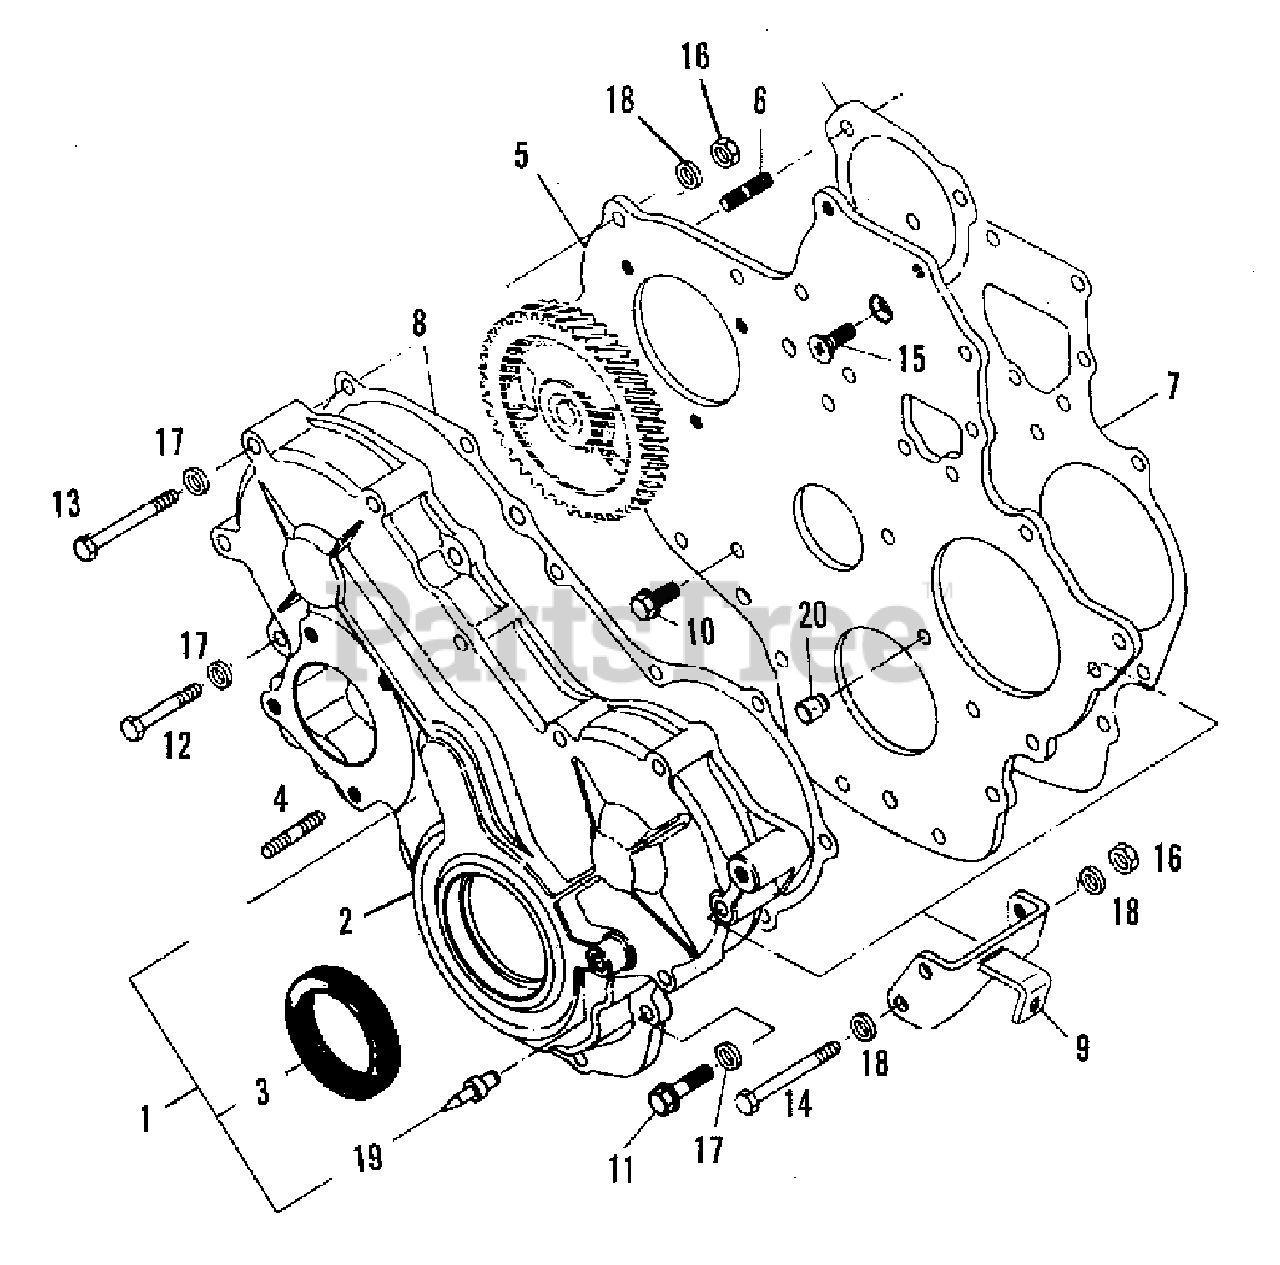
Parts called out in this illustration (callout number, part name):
1	COVER ASSEMBLY, gear (Incl. Item 2 thru 4 & 19)
3	SEAL, front oil
4	STUD, gear cover
5	PLATE ASSEMBLY, front (Incl. Item 20)
7	GASKET, front plate
8	GASKET, gear cover
9	BRACKET, generator
10	CAPSCREW, M8 x 20 w/lockwasher, front plate
11	CAPSCREW, M8 x 30 w/lockwasher, gear cover
12	CAPSCREW, M8 x 45 gear cover
13	CAPSCREW, M8 x 55 gear cover
14	CAPSCREW, M8 x 60 generator bracket to gear cover
15	SCREW, M8 x 20 front plate
16	NUT, M8 gear cover
17	WASHER, M8 gear cover
18	LOCKWASHER, M8 gear cover
19	POINT, timing
20	INJECTOR, oil
